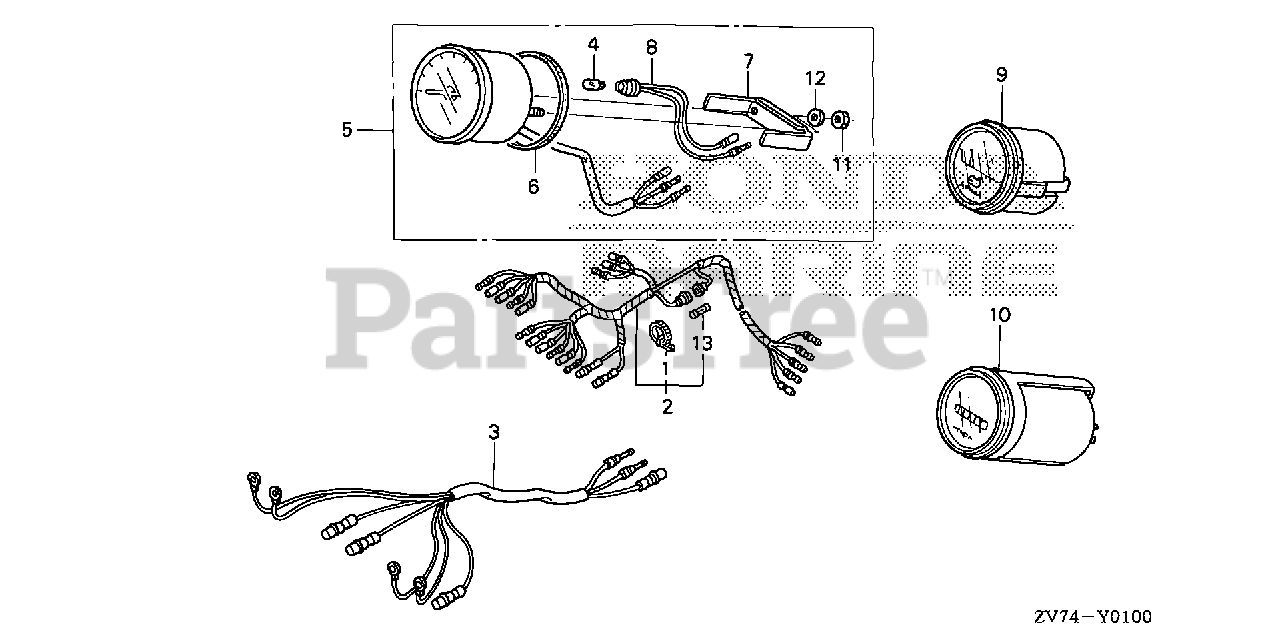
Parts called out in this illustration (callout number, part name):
1	BAND B1, WIRE
2	HARNESS ASSY., METER (A)
3	HARNESS ASSY., METER (B)
4	BULB, WEDGE BASE (T10) (12V 1.7W) (STANLEY)
5	TACHOMETER ASSY.
6	GASKET
7	BRACKET
8	SOCKET
9	METER ASSY., VOLT (NOT AVAILABLE)
10	METER ASSY., HOUR L.C.D.
11	NUT, HEX. (5MM)
12	WASHER, SPRING (5MM)
13	FUSE A (10A)
